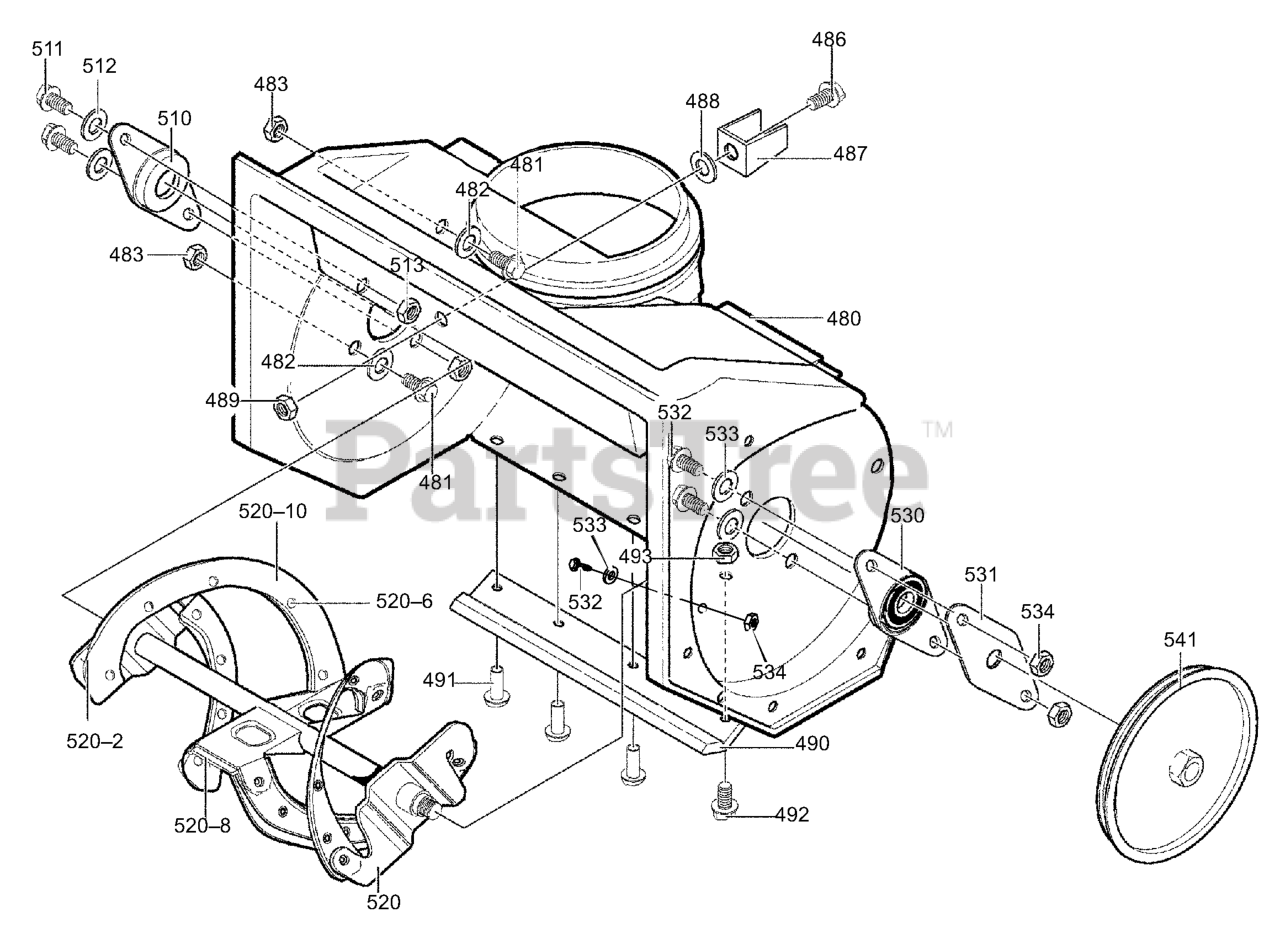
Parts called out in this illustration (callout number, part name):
480	HOUSING, ASSY
481	SCREW, 1/4-20X.75
482	WASHER, FLAT .281X.63X.065
483	NUT, 1/4-20 REGHEXCTRLK
486	SCREW, 1/4-20X.63
487	BRACKET, STOP
488	WASHER, FLAT .333X.87X.119
489	NUT, 1/4-20 HEX NYLOCK
490	BLADE, SCRAPER
491	RIVET, OVSET .250DIAX.61LG
492	SCREW, 1/4-20X.75
493	NUT, CNTRLK 1/4-20
510	BEARING, FLANGE
511	SCREW, 1/4-20X1.00
512	WASHER, FLAT .281X.63X.065
513	NUT, CNTRLK 1/4-20
520	AUGER, ASSY
520-2	BLADE, AUGER
520-6	RIVET
520-8	BLADE, CENTER
520-10	AUGER & BLADE SUPPORT
530	BEARING & PLATE ASSY
531	PLATE, RETAINER
532	SCREW, 1/4-20X.63
533	WASHER, FLAT .281X.63X.065
534	NUT, 1/4-20 REGHEXCTRLK
541	PULLEY V3L 6.00 O.D.
